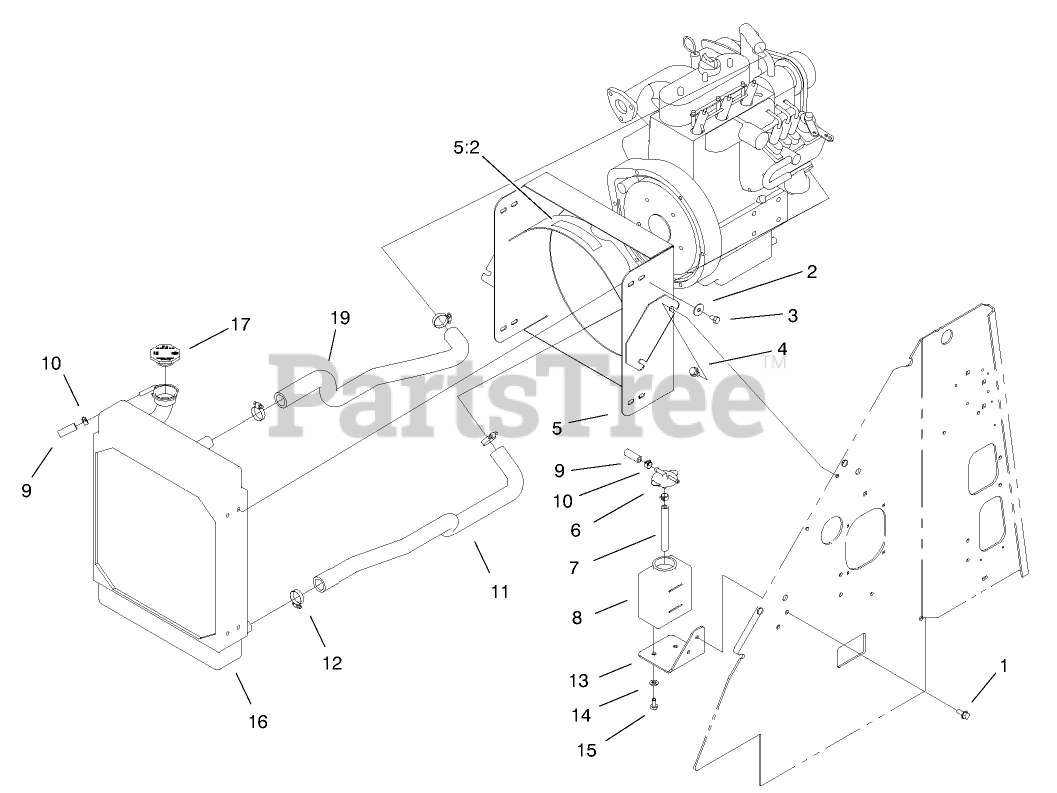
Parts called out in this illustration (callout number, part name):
1	SCREW-HWHTF
2	WASHER-FLAT
3	SCREW-HH
4	SCREW-HWHTF
5	ShroudASM
5:2	DECAL-WARNING, FAN
6	CAP-TANK, OVERFLOW
7	HOSE-FUEL
8	TANK-OVERFLOW
9	HOSE-FUEL
10	CLAMP-HOSE
11	HOSE-RADIATOR, LOWER
12	CLAMP-HOSE
13	MOUNT-TANK, OVERFLOW
14	WASHER-PLAIN
15	BOLT
16	RADIATOR
17	CAP-RADIATOR
19	HOSE-RADIATOR, UPPER
